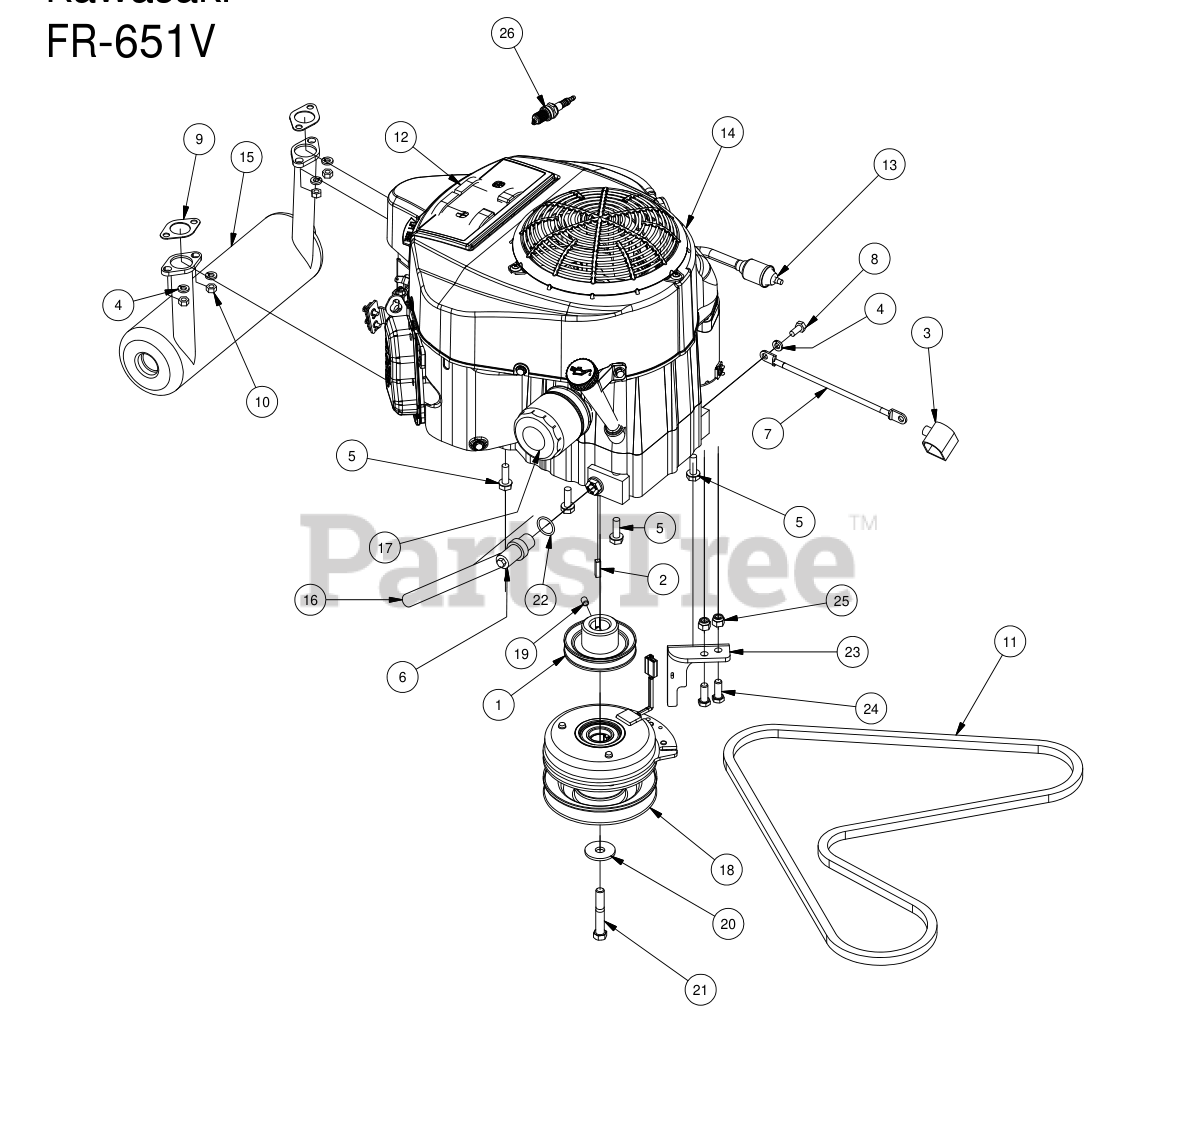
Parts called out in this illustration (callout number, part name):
1	3-3/4" Motor Pulley
2	1/4" x 1" Key
3	Black Boot For Ground Cable
4	5/16" Lock Washer
5	3/8 x 1 1/8 bolt
7	Ground Cable
8	M8x1.20x20MM Hex head bolt
9	Exhaust Gasket
10	M8-1.25 Zinc Nut
12	Kawasaki Air Filter
13	Universal Inline Fuel Filter
14	726cc Kawasaki Engine-FR651V
15	Exhaust for FR Kawasaki-MZ
16	1/2 Clear Braded Hose Priced/Foot
17	Kawasaki Oil Filter
18	Clutch 2015 Magnum/MZ
19	3/8" Set Screw
20	1/2 Belleville Washer
21	7/16"-20 x 4" Hex Bolt Gr. 8
23	Warner Clutch A-R Bracket
24	3/8" x 1" Hex Bolt
25	3/8 Nylock Nut
26	Spark Plug - Kawasaki
